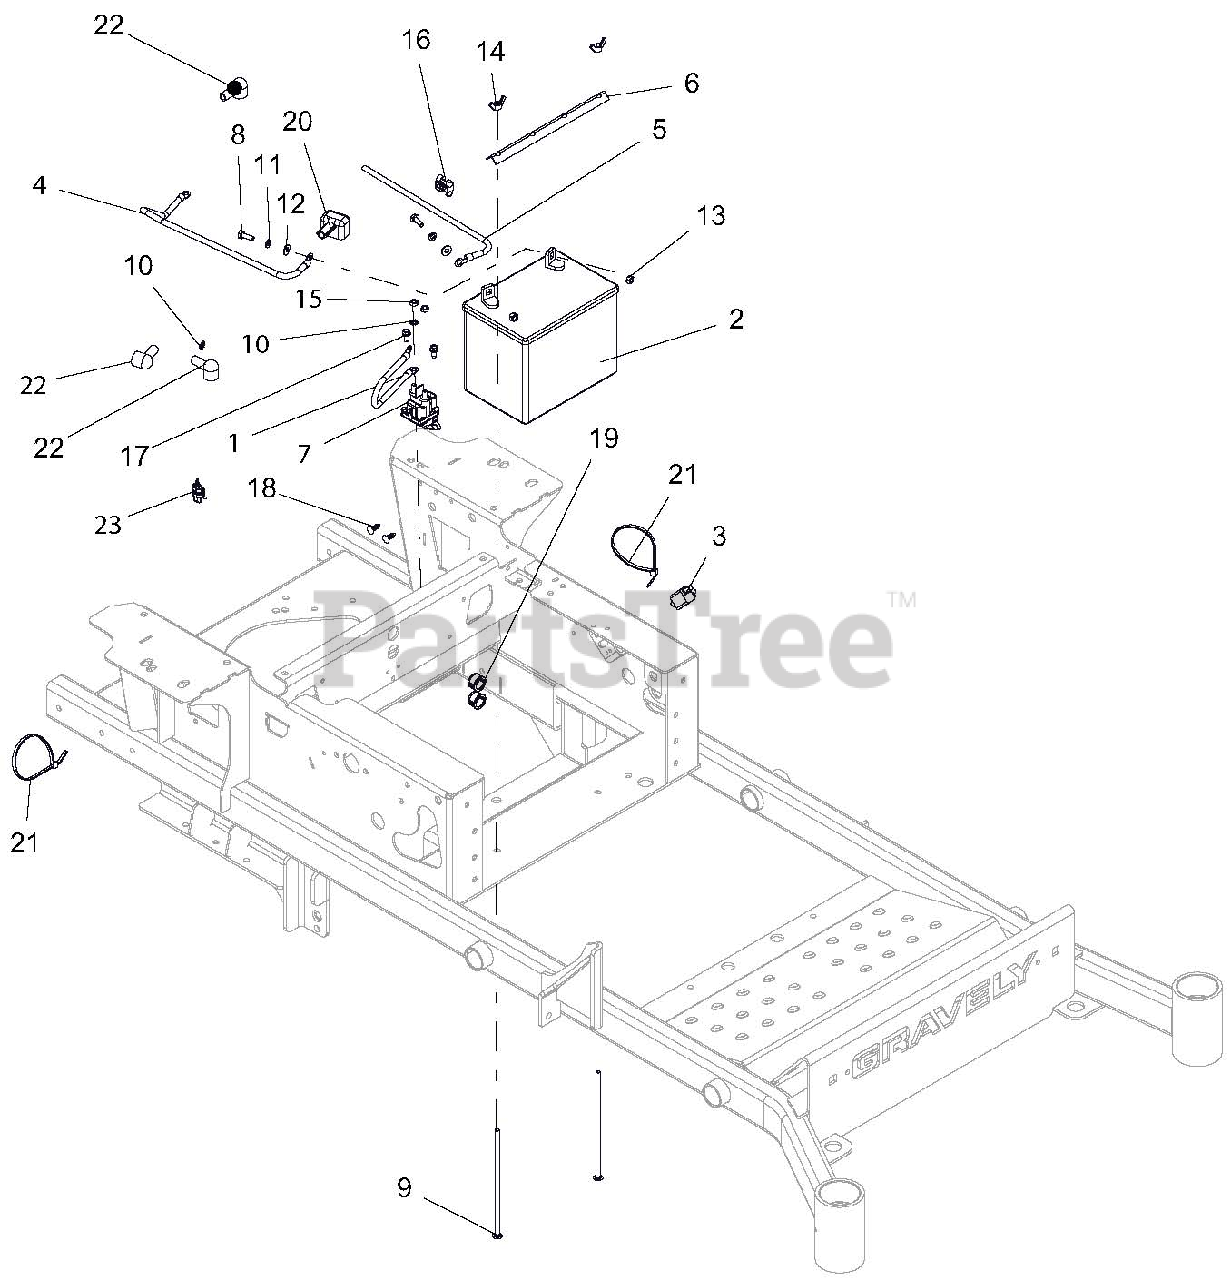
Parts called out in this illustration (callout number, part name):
1	CABLE, POS W/(2) 1/4 RING 9.0 LG
2	BATTERY, 300 CCA 10U1L
3	SWITCH, SINGLE POLE N.O.
4	CABLE, POS W/(2) 1/4 RING 9.0 LG
5	CABLE, NEGATIVE BATTERY 24"
6	HOLD DOWN - BLK
7	SOLENOID, STARTER
8	BLT-HEX .25-20X.75 GR5 YWZC
9	BLT-RDHDSQNK .25-20X7.50 G2 YWZC
10	@, WSHR-LK-EXT.262X.502X.026 YWZC
11	WSHR-LK .25X.062 REG YWZC
12	WSHR-FL-STL.281X.62X.065 YWZC
13	NUT-HEX .25-20 YWZC
14	NUT-LOCKING WING 1/4-20
15	NUT-HEX M6-1.00 YWZC
16	CLIP, T, .318-.3
17	SCR-TAP .25-20X.50 HWH TR YWZ
18	RIVET, .25 NYLON PANEL
19	BUSH, PANEL SNAP .687X.875X.56
20	INSULATOR
21	CABLE, TIE 5.50 LG
22	BOOT, EYELET TERMINAL
